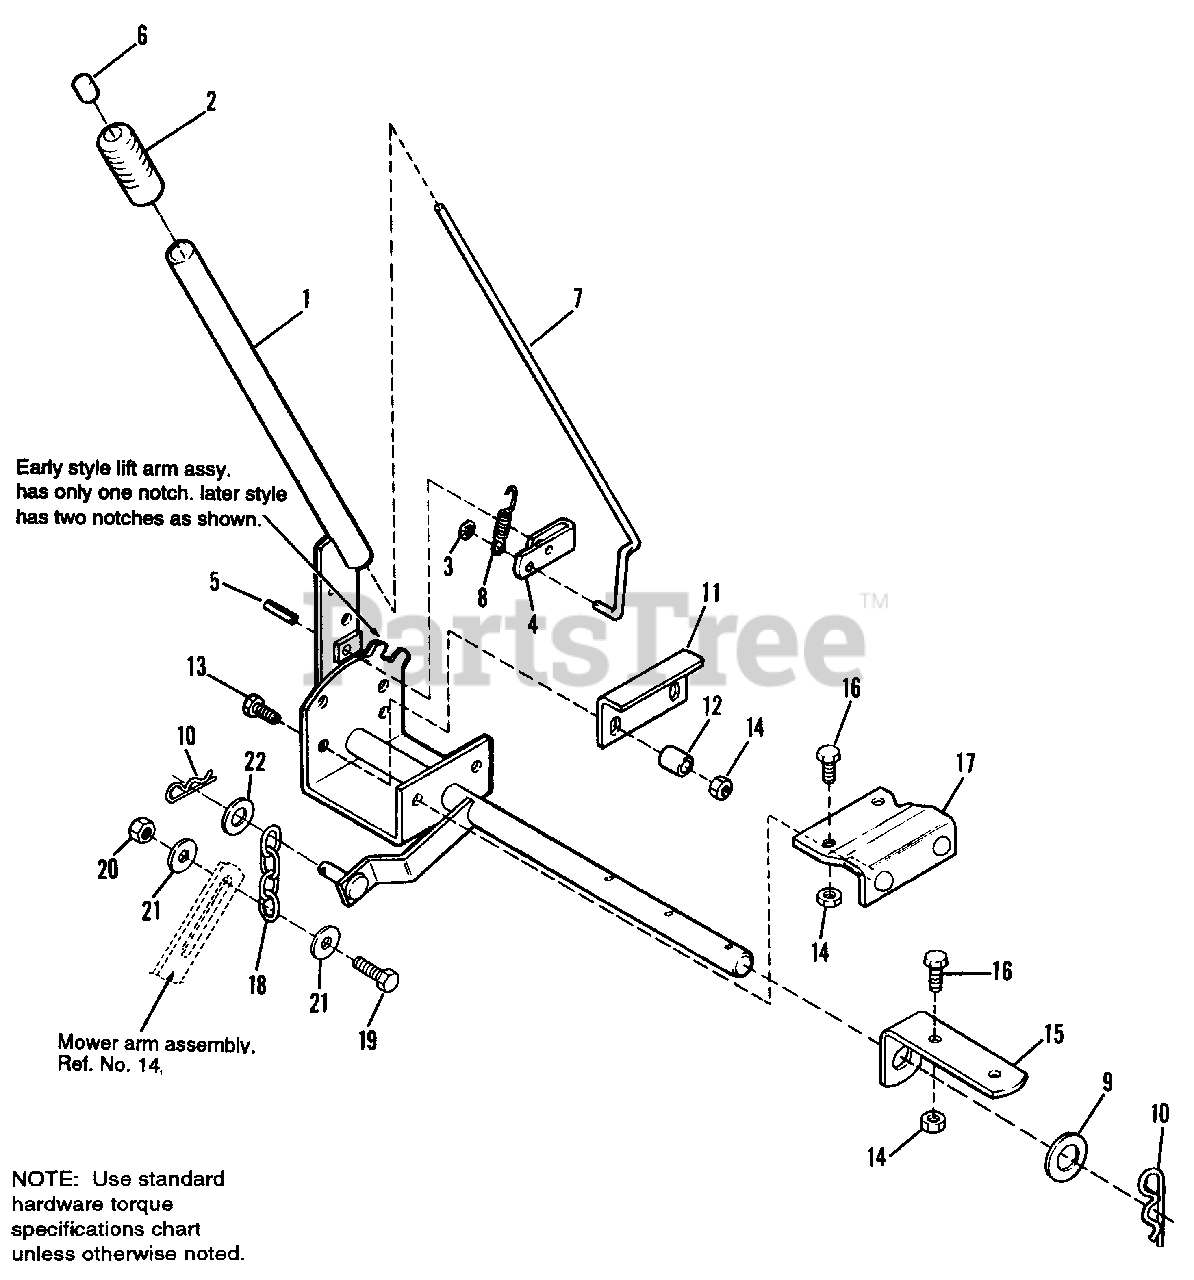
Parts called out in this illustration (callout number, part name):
1	LEVER ASSY., Lift (Early models only)
1	LEVER ASSY., Lift (Later models only)
2	GRIP, Lift Lever
3	NUT, Push-On
4	LATCH, Lift Lever
6	BUTTON, Thumb
9	WASHER, Flat
10	CLIP, Hair Pin (Qty. 2 on earlier models)
11	BRACKET, Guide, Lift
13	CAPSCREW, Hex Hd., 5/16-18 x 1-1/4
14	NUT, Hex, Lock, ESNA, 5/16-18
15	BRACKET, Pivot, Lift
16	CAPSCREW, Hex Hd., 5/16-18 x 7/8
17	BRACKET ASSY., Lift Mounting
18	CHAIN, Lift, 4 Link (Early models only)
19	CAPSCREW, Hex Hd., 5/16-18 x 1-1/2 (Early models only)
20	NUT, Hex, Lock, Full, 5/16-18 (Early models only)
21	WASHER, Flat (Early models only)
22	WASHER, Flat (Early models only)
